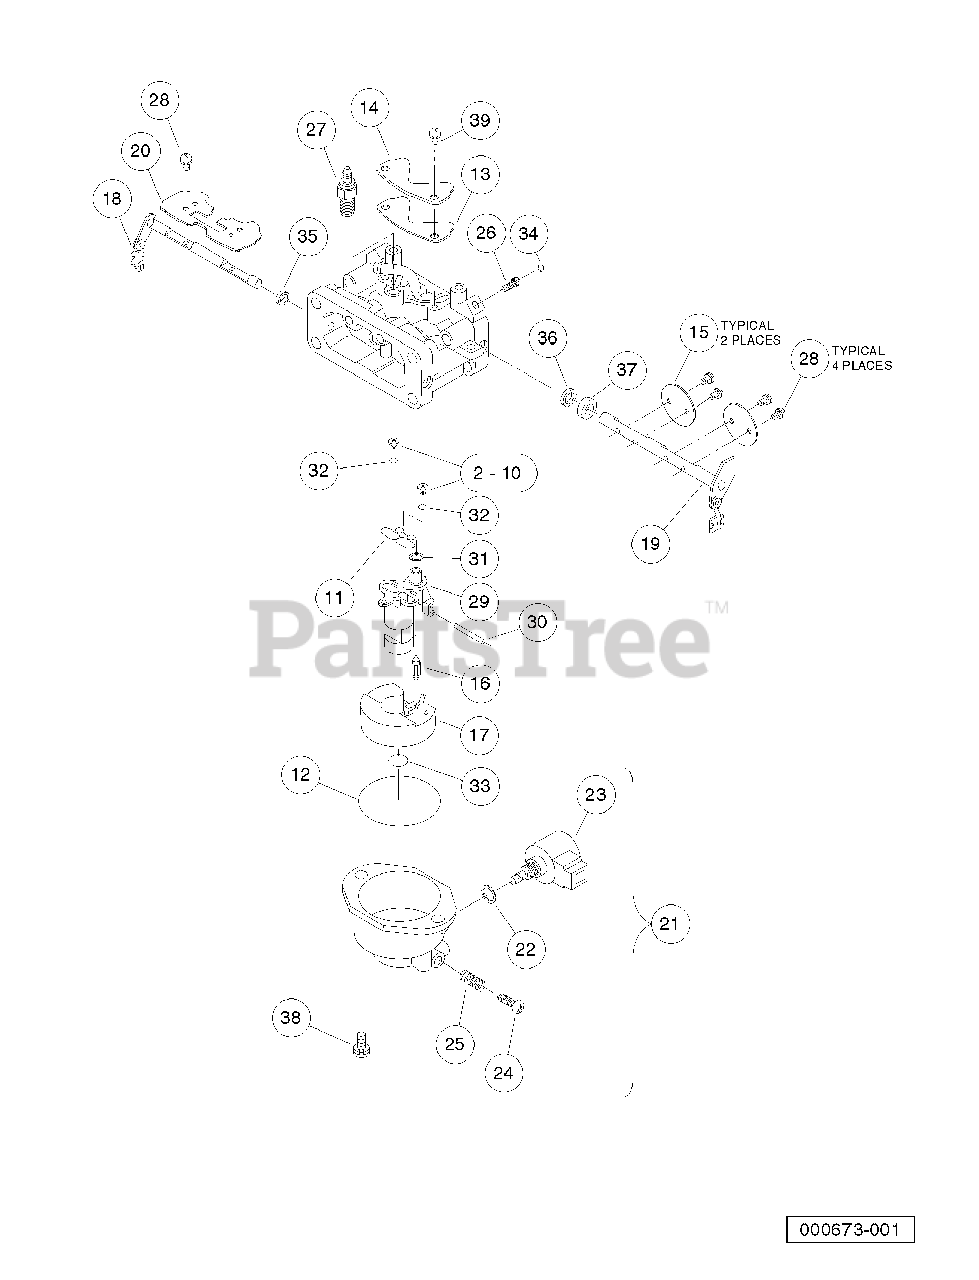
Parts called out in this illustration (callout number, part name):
1	Asm, Carburetor, Fh680d
2	Kit, Jet, 6600 Ft +, Fh680d
4	Kit, Instructions Jet, Push In
5	Kit, Jet, 3300-6600 Ft, Fh680d
7	Kit, Instructions Jet, Push In
8	Kit, Jet, 0-3300 Ft, Fh680d
10	Kit, Instructions Jet, Push In
11	Gasket, Fh680d
12	Gasket, Carburetor, Dia. 52
13	Gasket, Cover, Fh680d
14	Cover, Slow Passage, Fh680d
15	Valve, Throttle, Fh680d
16	Valve, Float, Fh680d
17	Float, Carburetor, Fh680d
18	Shaft, Carburetor, Fh680d
19	Shaft, Carburetor, Throttle
20	Valve, Carburetor, Fh680d
21	Asm, Chamber, Float, Fh680d
22	Gasket, Carburetor, Fh680d
23	Solenoid, Carburetor, Fh680d
24	Screw, Drain, Carburetor
25	Spring, Carburetor, Fh680d
26	Needle, Jet, Fh680d
27	Heater, Carburetor, Fh680d
28	Screw, Carburetor, M3 X 6
29	Spacer, Carburetor, Fh680d
30	Pin, Carburetor, Fh680d
31	O-ring, Carburetor, Dia. 6.5
32	O-ring, Carburetor, Fh680d
33	O-ring, Carburetor, Dia. 9
34	Plug, Expansion, Carburetor
35	Seal, Carburetor, Dia. 5.9
36	Seal, Carburetor, Fh680d
37	Collar, Carburetor, Fh680d
38	Screw, Carburetor, M5
39	Screw, Carburetor, M4
